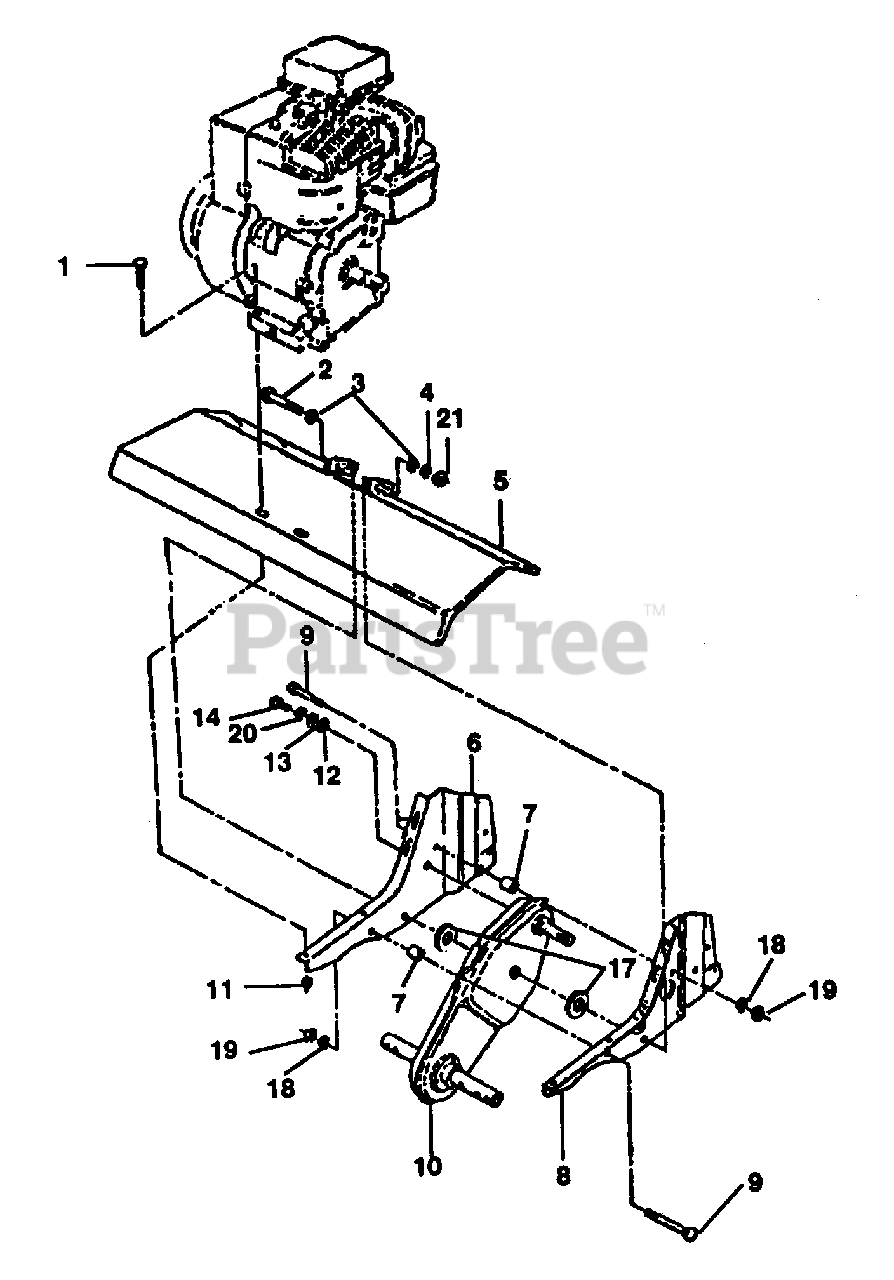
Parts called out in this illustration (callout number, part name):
1	Bolt, Hex 5/16-18 x 1-1/2 Gr. 2 (AYP part number)
2	Bolt, Hex 3/8-24 x 3-1/4 Gr.5 (AYP part number)
3	Washer 13/32 x 13/16 x 11 (AYP part number)
4	Washer, Lock 3/8 (AYP part number)
5	Shield, Tine (AYP part number)
6	Bracket, Engine, R.H. (AYP part number)
7	Spacer, Split (AYP part number)
8	Bracket, Engine, L.H. (AYP part number)
9	Bolt, Hex 5/16-18 x 2-3/4 (AYP part number)
10	Transmission
11	Nut, Keps 5/16 (AYP part number)
12	Washer 9/32 x 7/8 x 12 Ga. (AYP part number)
13	Washer 9/32 x 1-1/4 x 16 Ga. (AYP part number)
14	Bolt, Hex 1/4-28 x 3/4 Gr. 5 (AYP part number)
17	Washer 17/32 x 1 x 16 Ga. (AYP part number)
18	Washer, Lock 5/16 (AYP part number)
19	Nut, Hex 5/16-18 (AYP part number)
20	Lockwasher 1/4 (AYP part number)
21	Locknut 3/8-24 (AYP part number)
